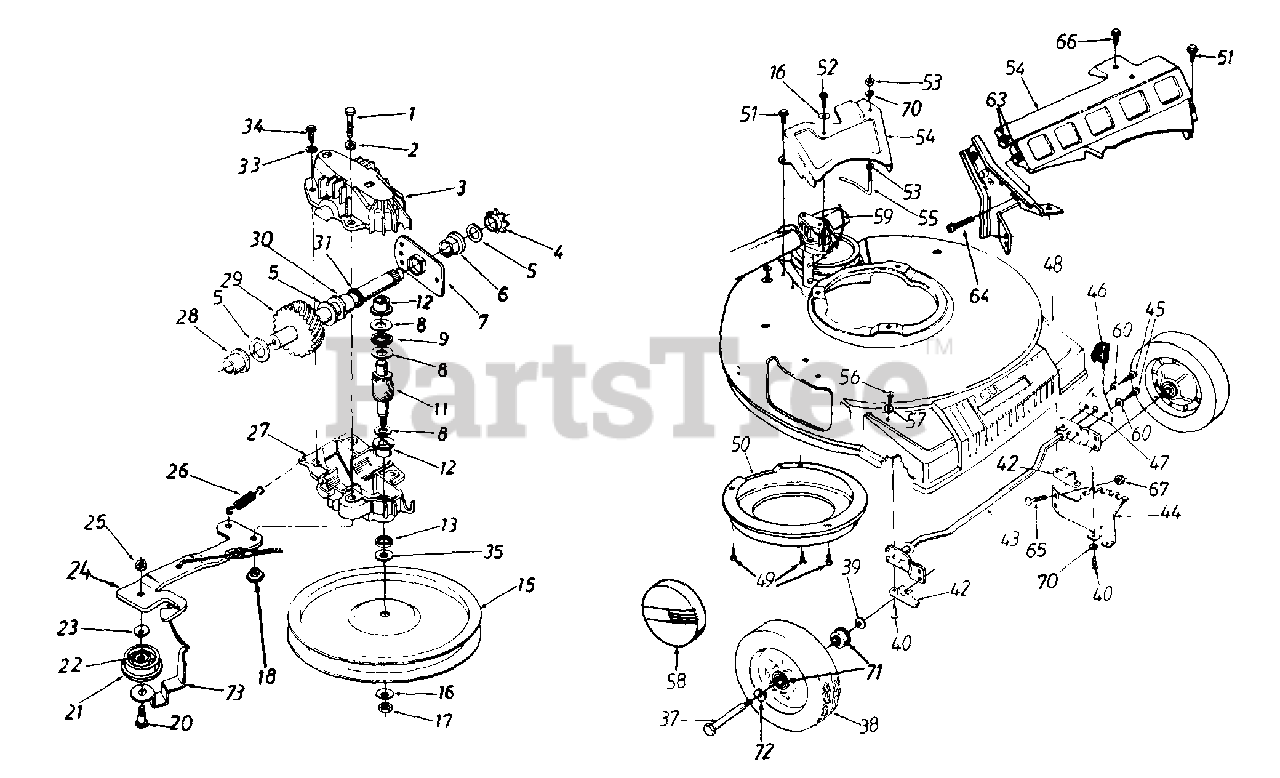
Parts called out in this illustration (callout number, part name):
1	Hex Patch Bolt 1/4-20 x 1.25"
2	L-Wash. 1/4" I.D.
3	Upper Hsg. Half
4	#48 Sprocket 7 T x 1/2 Pitch
5	Fl-Wash. 5/8" I.D. x .030
6	Hex Flange Brg. .631" I.D.
8	Thrust Wash. .382" I.D. x .70" O.D.
9	Thrust Bearing .375" I.D. x .812" O.D.
11	11 Tooth Pinion Shaft
12	Flange Bearing
13	Oil Seal
15	Fl-Pulley 5.06" O.D.
16	Bell-Wash. .265" I.D. x .75"
17	Hex L-Nut 1/4-28 L.H. Thd.
18	Shld. Spacer .375" Dia. x .170
20	Shld. Bolt .375" Dia. x .40"
21	Fl-Idler Plastic 1.50" Dia.
22	Needle Brg. .375" x .31
24	Idler Brk't. Ass'y.
25	Hex Patch L-Nut 1/4-28 Thd.
26	Extension Spring 1.12" Lg.
27	Lower Hsg. Half
28	Flange Bearing .566 Dia.
29	Shaft Ass'y.
30	Flange Bearing .629 Dia.
31	Oil Seal .625 Dia.
33	L-Wash. #10 I.D.
34	Hex B-Tap Scr. #10 x .62"
35	Hex Washer .26" x .88"
37	Front Axle Bolt
38	Wheel Ass'y. Comp. (Gray Rim)
39	Bell-Wash. .380" I.D. x .88
40	Hex Wash. Hd. Scr. 1/4 x 1" Lg.
42	Block Bushing
45	Hex TT-Tap Scr. 1/4-20 x .38"
46	Knob
47	Spring Lever
48	Plastic Front End (Black)
49	Hex B-Tap Scr 1/4" x .38"
52	Hex Wash. Hd. B-Tap Scr. 1/4 x .62" (Spec.)
53	Hex Nut 1/4-20 Thd.
56	Torx Truss Hd. Scr. 5/16 x .75"
57	Bell-Wash. .345" I.D. x .88"
58	Hub Cap
59	S.P. Cable
60	External L-Wash. 1/4" I.D.
63	Speed Nut #10-24 Thd.
64	Hex Tap Scr #10-16 x .5" Lg.
65	Carr. Bolt 1/4-20 x 5" Lg.
66	Hex B-Tap Scr. 5/16-18 x .5" Lg.
67	Hex Flange L-Nut 1/4-20 Thd.
70	L-Wash. 1/4" I.D.
71	Wheel Bearing
72	Wave Washer
